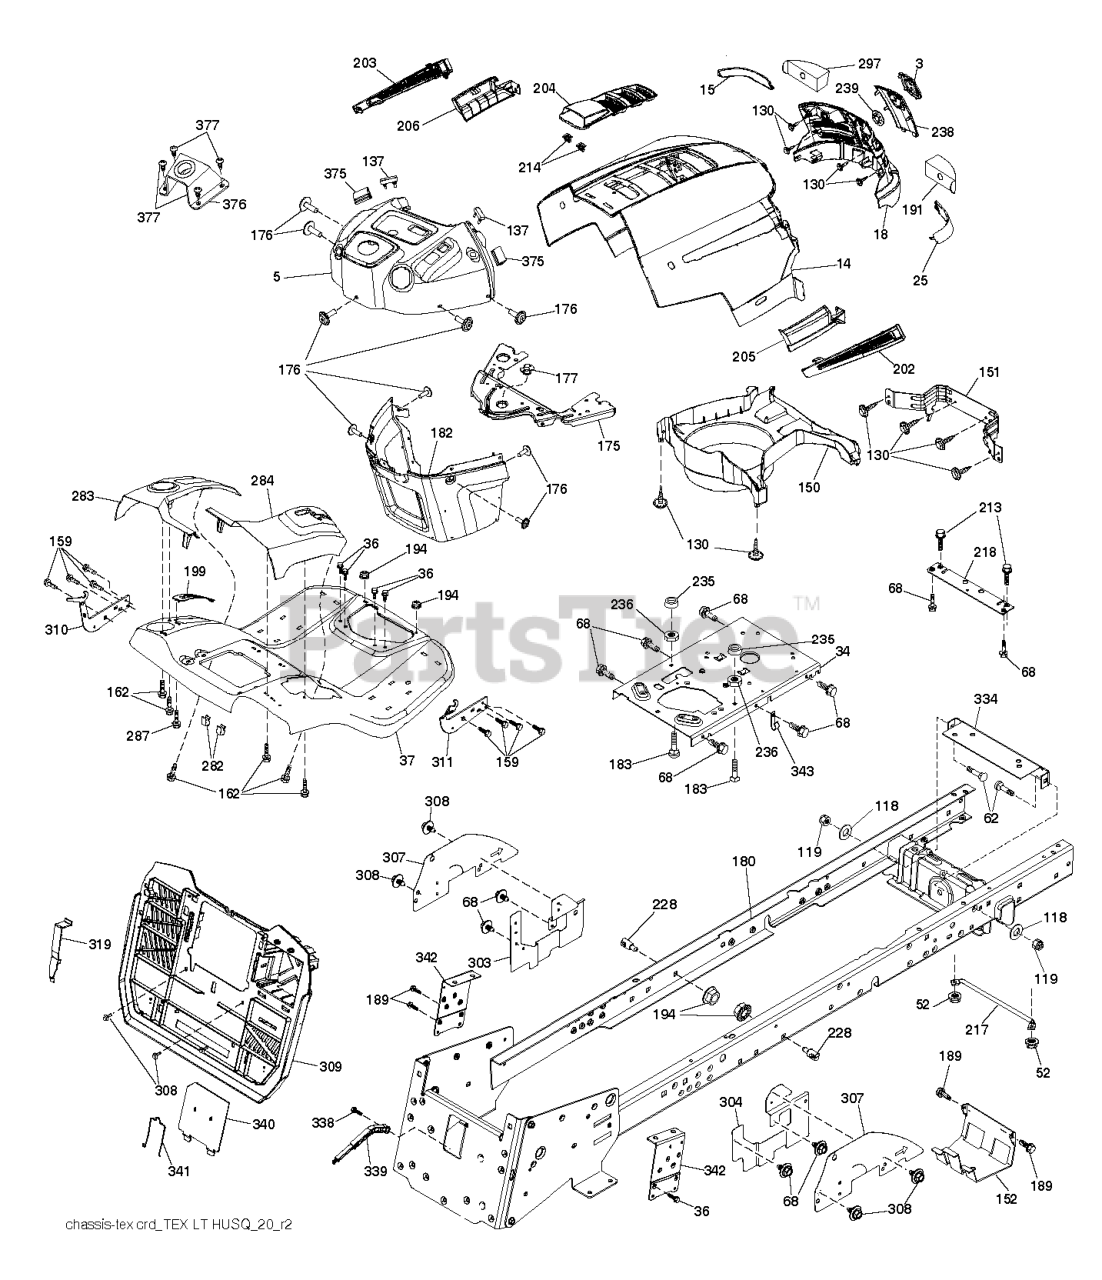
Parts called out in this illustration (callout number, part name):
3	LOGO.HUSQ.GT.LT.CROWN.H
5	DASH.UPPER.HUS.LT.CABLE.CLUTCH
14	HOOD.HUSQVARNA.LT.ORANGE
15	LENS.HUSQVARNA LT.RH
18	ASM.GRILLE HUSQVARNA.LT.498
25	LENS.HUSQVARNA LT.RH
36	SCREW 5/16"
37	FENDER.TEX.SRD.CRD.FRN.GUARDS
118	WASHER PLAIN WASHER 3/8 X 0.08
137	BUMPER DASH
151	BRACKET PIVOT
152	SHIELD.BROWNING.W/TEX
159	SCREW, 3/8-16X3/4
175	CROSSMEMBER
176	SCREW.#10-24X5/8.RN.QU
177	BUSHING STEERING
180	CHASSIS WLDT TEX CRD
182	DASH.LOWER.PREDATOR LT
189	SCREW
191	INSERT.REFLECTIVE.RH.
199	PLATE DECK LIFT
202	VENT.SIDE.HUSQVARNA.LT.RT
203	VENT.SIDE.HUSQVARNA.LT.LFT
204	SUBASM.TOP.VENT.HUSQ.LT
205	SKIRT.SIDE.HUSQVARNA.LT.RT
206	SKIRT.SIDE.HUSQVARNA.LT.LEFT
213	SCREW HEXAGON HEAD SCREW 5/16-
214	CLIP.RETAINER.TINNER.
217	ROD.PIVOT.HOOD
218	X-PIECE.HOOD.STOP.NON/
228	STUD.W/"D"ANTI-ROTATION
236	NUT.CENTERLOCK.5/16-
238	TRIM.HUSQ LT.668
282	CLIP.RETAINER.CONSOLE.LT.HUSQ
283	CONSL.DECKLIFT.LH.SRD.TEX.CRD
284	CONSL.SHFT.PEDAL.RH.SRD.TEXCRD
287	SCREW 1/4X20
297	INSERT REFLECTIVE
303	SHIELD.LWR.LH.30DECK/CRD1&2
304	SHIELD ISO RH LOWER CRD GEN 1
307	SHIELD.UPPER.CRD.SRD.ISO
308	BOLT.5/16-18UNCX3/4 W/SEMS.BLK
309	BACKPLATE.TEX.CRD.GEN.1
310	BRACKET BRACKET.LH REAR BAG HA
311	BRACKET BRACKET.RH REAR BAG HA
319	BRACKET.ACTUATOR.BAGGER.SRD
334	BRACKET.ENGINE
339	LEVER LEVER BAGGER
340	DOOR.PNT.BATTERY.TRY.TEX.CRD.
341	LATCH.BATTERY.DOOR.TCRD
342	SUPPORT.PNT.FENDER.CRD.TEX
343	CLIP CLIP
375	BUMPER CLIP-ON. DASH 1"
376	MOUNT.ASM.HUSLT.UPPER.STRNG
377	SCREW 10 X 1/2 ZN PL PHIL PAN
